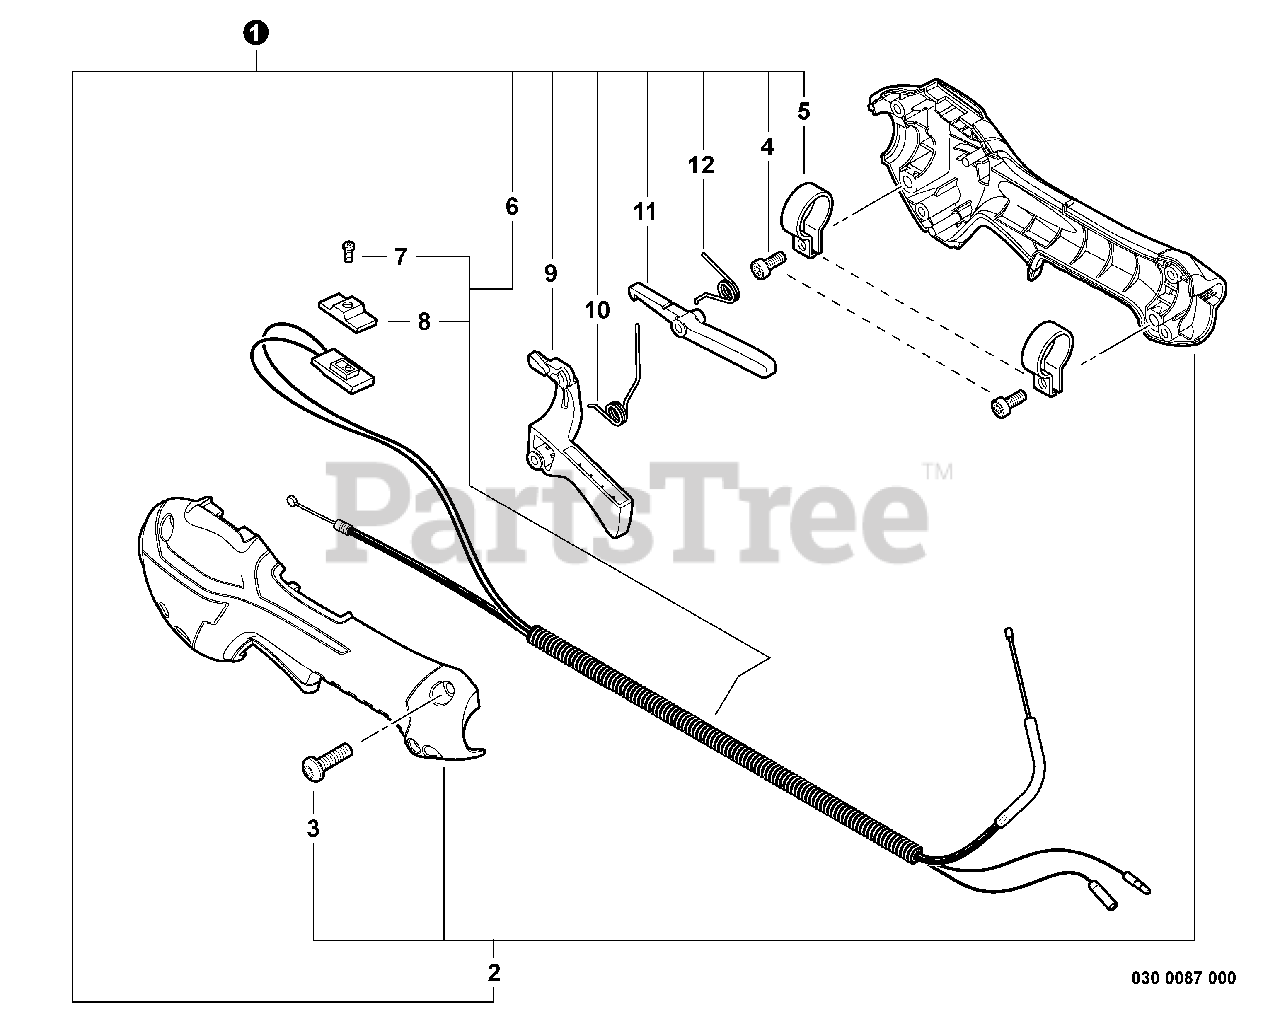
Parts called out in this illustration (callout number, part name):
1	GASKET KIT
2	GASKET, CRANKCASE
3	GASKET, CYLINDER
4	HEAT SHIELD, INTAKE
5	GASKET, INTAKE
6	HEAT SHIELD, EXHAUST
7	GASKET, EXHAUST
8	TUNE-UP KIT - REPOWER
9	PRE-FILTER, FOAM
10	FILTER, AIR - DOUBLE LAYER
11	FILTER, FUEL
12	SPARK PLUG - BPMR8Y
13	FUEL SYSTEM KIT
14	VENT ASSY
15	CLIP Ø6.5 MM
16	PIPE, FUEL 3×6×35 BLACK
17	PIPE, FUEL 3×5×195 BLACK
18	PIPE, FUEL 3×6×75 CLEAR
19	GROMMET, FUEL
20	CLIP Ø6
21	FILTER, FUEL 125-528
22	FUEL SYSTEM KIT
23	VENT ASSY
24	CLIP Ø6.5 MM
25	PIPE, FUEL 3×6×35 BLACK
26	PIPE, FUEL - 3×5×67 - BLACK
27	PIPE, FUEL 3×6×75 CLEAR
28	GROMMET, FUEL
29	CONNECTOR, PIPE Ø5ר3.5
30	CLIP Ø6
31	PIPE, FUEL - 3×5×125 - BLACK
32	FILTER, FUEL 125-528
33	GASKET, FUEL CAP
34	CAP/VENT KIT - REPOWER
35	CAP, FUEL
36	VENT ASSY
37	GASKET, FUEL CAP
38	BULK PIPE - 3×5 MM BLACK (4 PIECES×2 M)
39	BULK PIPE - 3×6 MM CLEAR (4 PIECES×2 M)
40	BULK PIPE - 3×6 MM BLACK (4 PIECES×2 M)
41	BULK STARTER ROPE - Ø 3.0 MM×61 M
